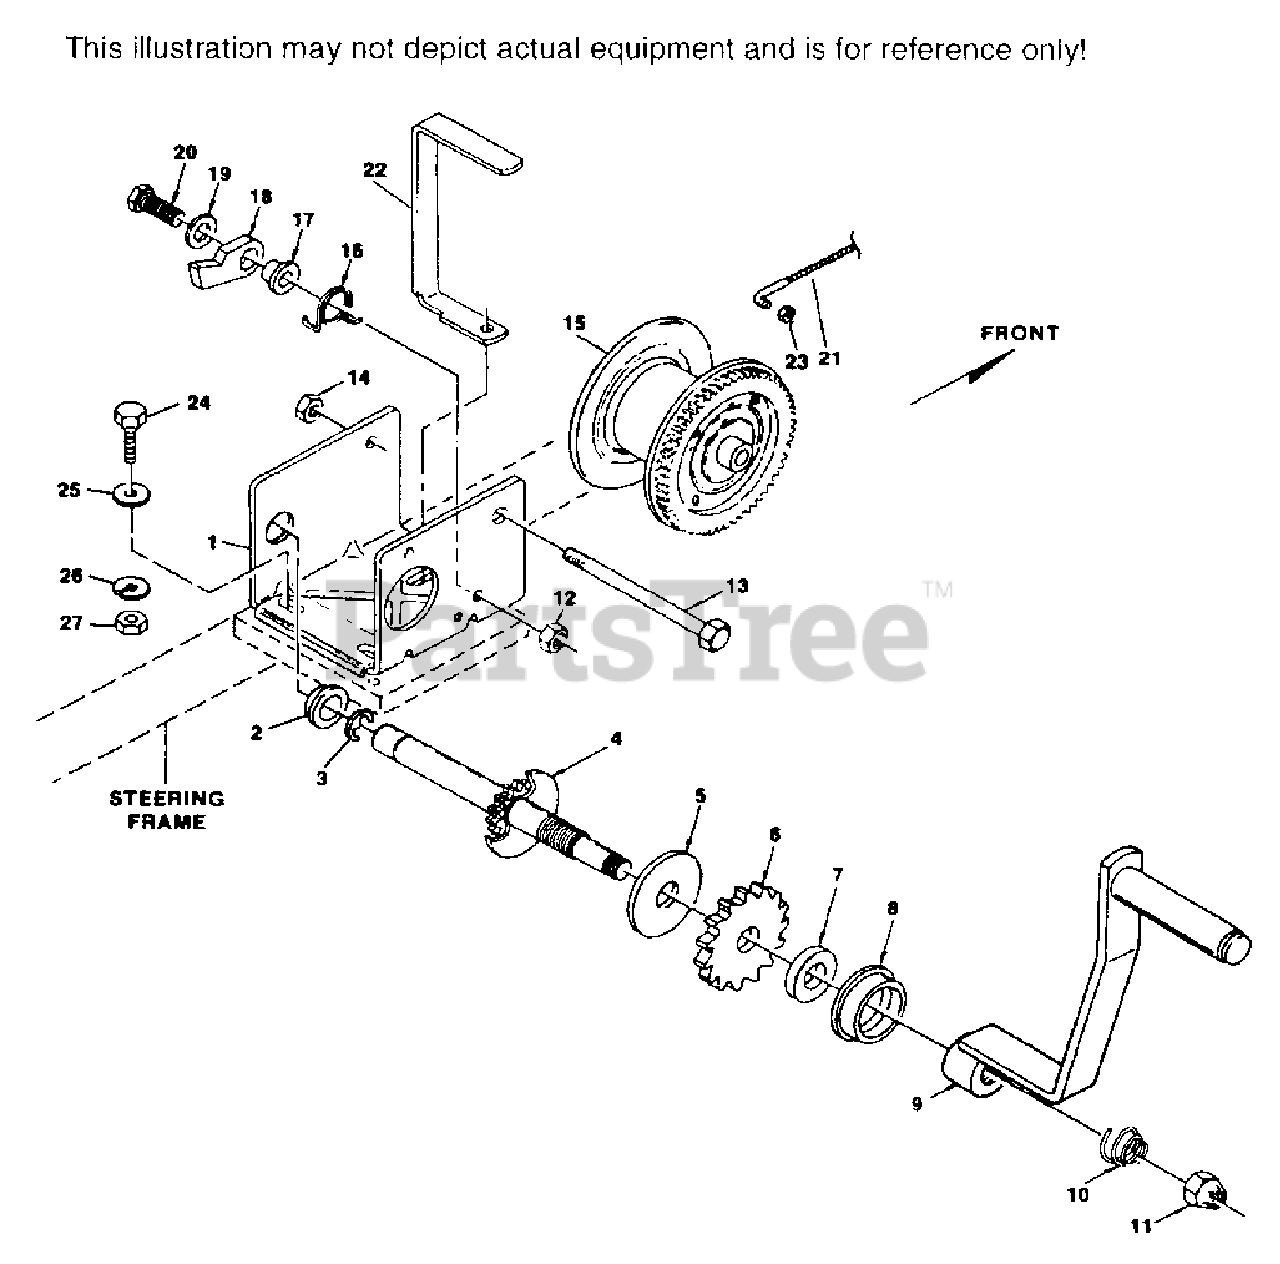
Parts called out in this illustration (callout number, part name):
1	WINCH ASSEMBLY(INCL. 1-8, 10-20)
2	SHAFT BUSHING
3	E-RING
4	DRIVE SHAFT
5	PRESSURE PLATE
6	RATCHET WHEEL
7	PRESSURE WASHER
8	SHAFT BUSHING
9	WINCH HANDLE
10	HANDLE SPRING
11	HANDLE NUT
12	HEX LOCKNUT, 3/8-16
13	REEL SHAFT
14	LOCK NUT, 7/16-14
15	WINCH REEL
16	RATCHET SPRING
17	RATCHET SPACER
18	RATCHET PAWL
19	FLAT WASHER
20	RATCHET BOLT
21	WINCH CABLE ASSEMBLY
22	CABLE GUIDE
23	HEX LOCK NUT, 1/4-28
25	FLAT WASHER, 13/32 X 13/16 X 16 GA.
26	LOCK WASHER, 3/8 SPRING
